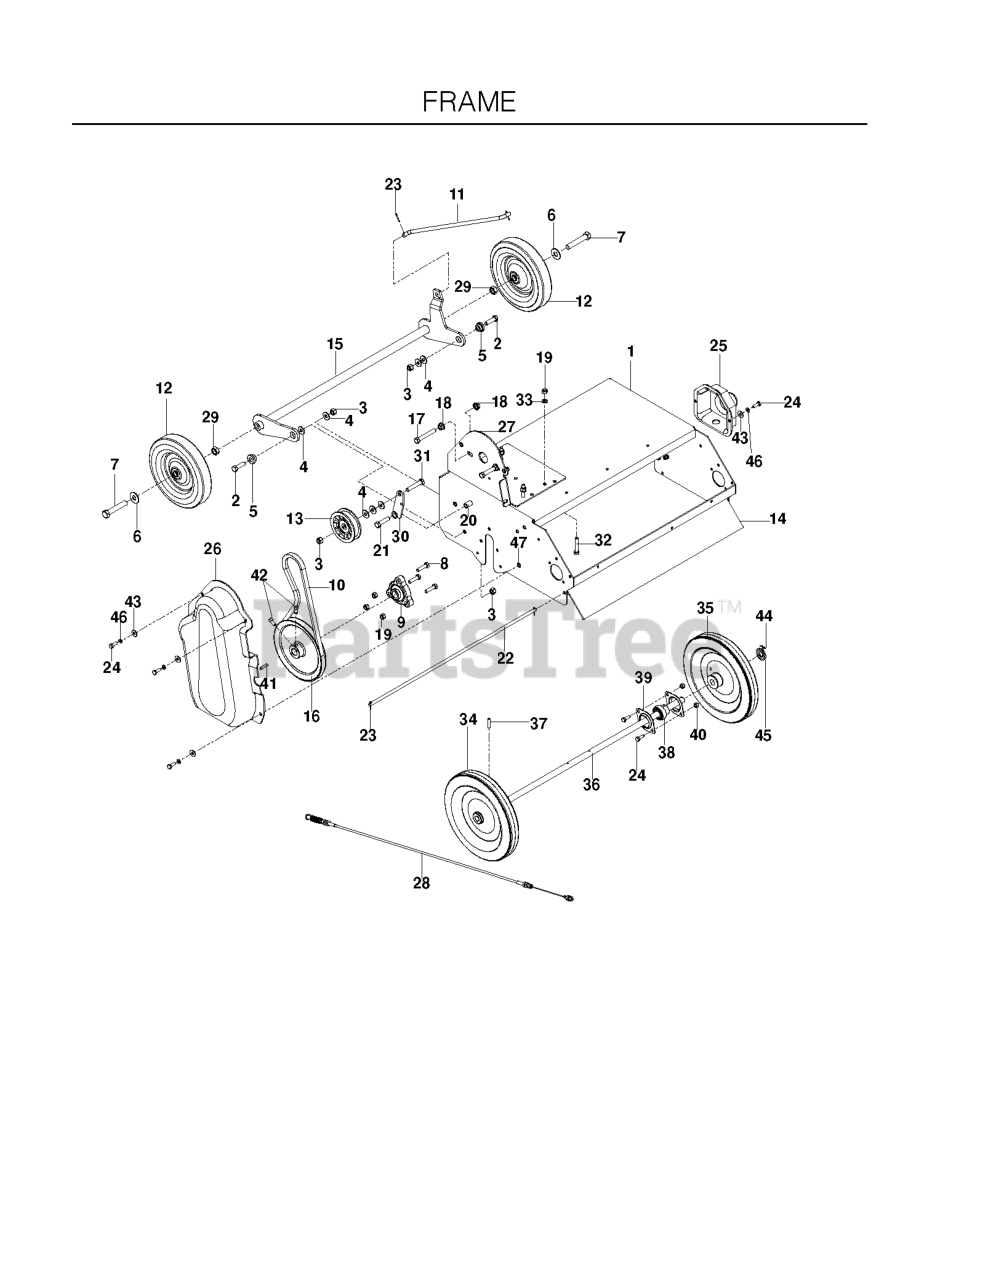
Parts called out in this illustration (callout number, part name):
1	WLDMT, BODY - ORANGE DT22
2	HCS 3/8C X 1 1/4 GR5
3	NUT 3/8-16 NYLOC
4	WASHER 5/16 FLAT
5	BUSHING RAKE
6	WASHER 1/2 FLAT
7	HCS 1/2C X 2 3/4
8	HCS 5/16C X 1 1/4
9	BEARING, FLANGED
10	BELT, DRIVE RAKE/SLICER DFS
12	WHEEL 8 X 1 3/4 RAKE
13	PULLEY, IDLER RAKE & ZTR
15	FRONT AXLE
16	PULLEY, MAIN SHAFT
17	HCS 3/8C X 2 1/2
18	NUT 3/8C WHIZ
19	NUT 5/16 NYLOC
20	BEARING, ONLITE RAKE/DT
21	HCS 3/8C X 1 1/2
23	COTTER PIN 3/32 X 3/4
24	HCS 1/4C X 3/4 HCS
25	SHAFT GUARD
26	BELT GUARD
27	BACKING PLATE ORANGE
28	CABLE POWER RAKE
29	NUT 1/2 HEX JAM
30	IDLER ARM - ORANGE
31	HCS 3/8C X 2
32	HCS 5/16C X 1 3/4
33	WASHER.LOCK.HVY.HLCL.SPR.5/16
34	WHEEL 10 X 1 3/4
35	WHEEL 10 X 1 3/4
36	AXLE, REAR
37	PIN ROLL 1/4 X 1-1/8
38	BEARING - 5/8" W/COLLAR
39	FLANGE BEARING ZINC PLATED
40	NUT.1/4-20.HEX.NYLOC.ZD
41	KEY, 3/16 SQUARE
42	SCREW 5/16C X 5/8 SQ HEAD
43	WASHER 1/4 FLAT
44	COTTER PIN
45	WASHER 5/8 FLAT
46	LOCKWASHER 1/4"
47	KNURLED INSERT
